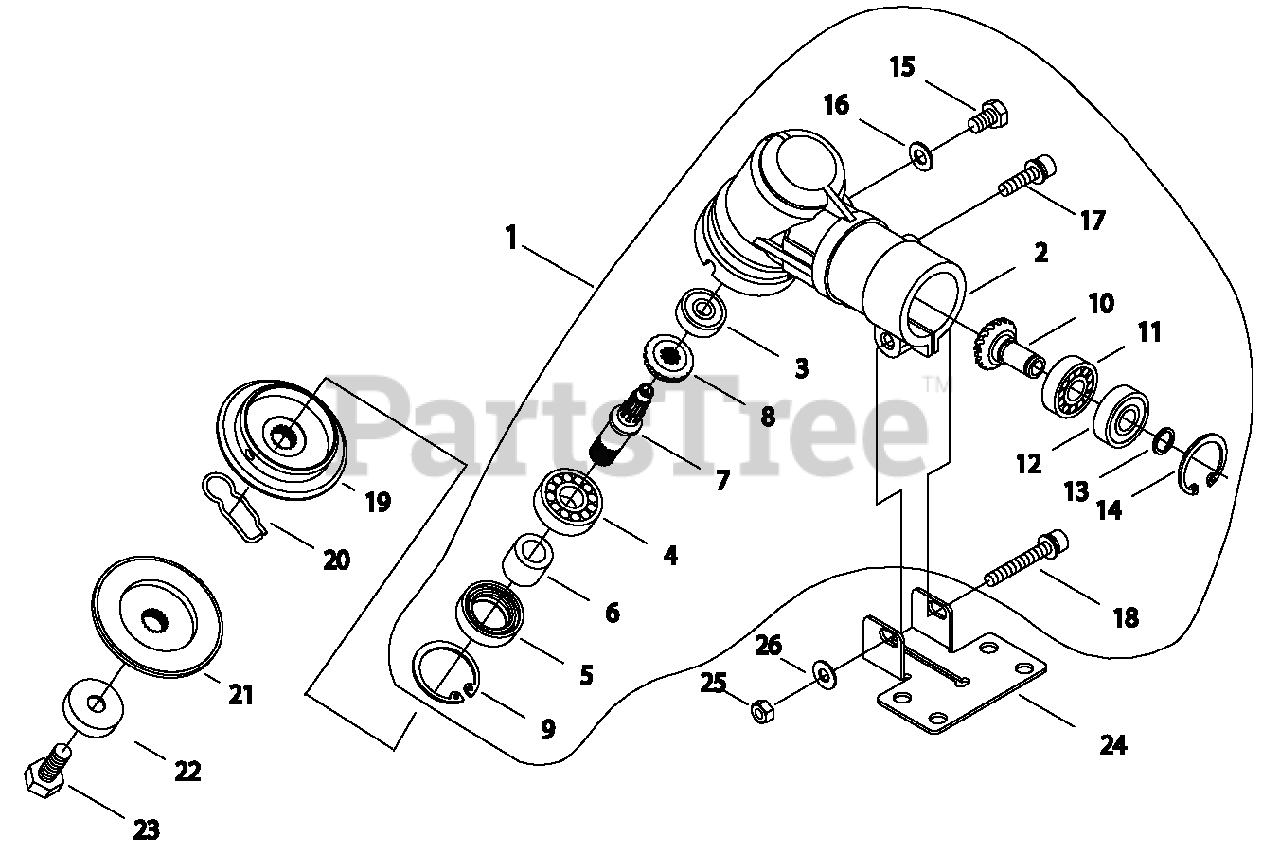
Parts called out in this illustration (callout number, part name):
1	GEAR CASE ASSY
2	CASE, GEAR
3	BEARING, BALL - 6000
4	BEARING, BALL - 6202
5	SEAL, OIL
6	COLLAR
7	GEAR - SHAFT
8	GEAR - BEVEL
9	RING, RETAINING - 35
10	GEAR - SHAFT
11	BEARING, BALL - 6001
12	BEARING, BALL - 6001ZZ
13	RING, RETAINING
14	RING, RETAINING - 28
15	BOLT - 6X10
16	WASHER
17	BOLT - 6X14
18	SCREW - 6X40
19	ADAPTOR, BLADE - UPPER
20	CLIP
21	ADAPTOR, BLADE - LOWER
22	GUARD
23	BOLT - 10 -- LEFT HAND
24	CLAMP - LOWER
25	LOCKNUT - 6
26	WASHER - 6
